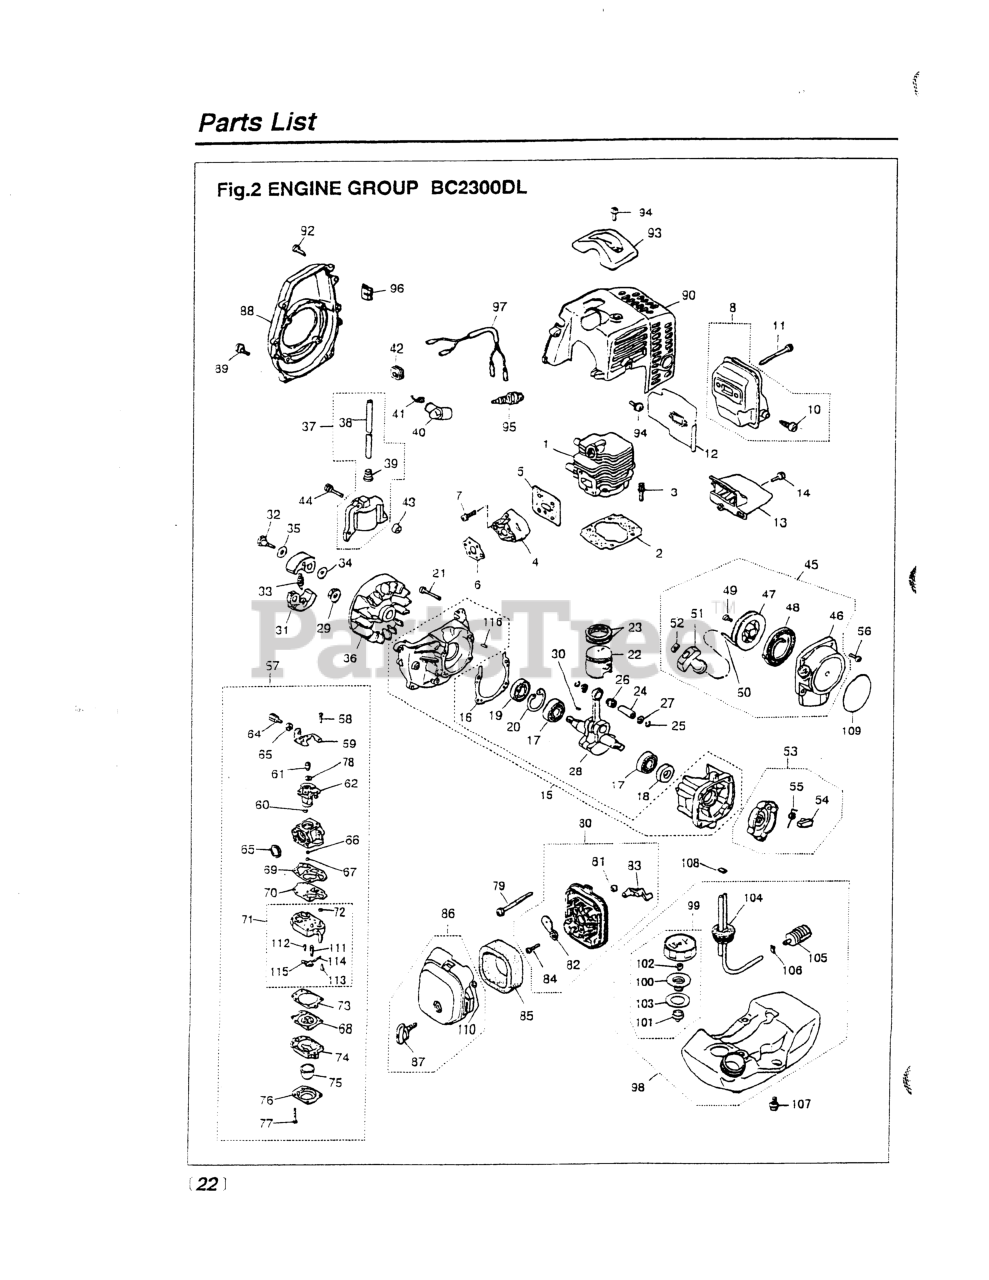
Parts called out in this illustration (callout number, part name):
1	CYLINDER
3	BOLT, M5 X 22
5	GASKET (RPLS -13120)
6	GASKET (REPLACES -13130)
7	SCREW, M5X20 (RPLS.1400-75510)
8	MUFFLER ASSY (RPLS 5501- )
10	ARRESTER (RPLS 5850-15140)
11	BOLT, M5 x 50
12	GASKET, MUFFLER (RPLS -15111)
14	SCREW, M4 X 16
15	CRANKCASE
16	GASKET (RPLS -21140)
17	BEARING
18	SEAL, OIL (RPLS 1100-21210)
19	SEAL, OIL (RPLS 1140-21220)
20	RING, SNAP, M28 x 1.2
21	BOLT, M5 X 30
22	PISTON (REPLACES 1140-41110)
23	RING, PISTON (RPLS 1850-41210)
24	PIN, PISTON 5x8x26
25	RING, SNAP (RPLS 1101-41320)
27	WASHER
28	CRANKSHAFT (RPLS 1850-42000)
30	KEY
31	SHOE (RPLS 1100-51114)
32	BOLT
33	SPRING, CLUTCH (RPLS-51220)
34	WASHER, FLAT (USE 182303)
36	ROTOR
37	COIL ASSY (RPLS 5500-71200)
38	CORD
39	CAP
41	SPRING
42	GROMMET
43	SPACER (RPLS -71260)
44	BOLT
45	RECOIL ASSEMBLY
46	CASE
47	REEL
48	SPRING, SPIRAL
49	SCREW (RPLS -75150)
51	KNOB
52	PLATE, STOPPER
53	PULLEY ASSY (RPLS -75210)
54	RATCHET (RPLS 1850-75220)
55	SPRING, RETURN
56	SCREW, M4 X 16
57	CARBURETOR
58	SCREW
60	RING
61	SWIVEL
62	VALVE ASSY
63	SCREW, CABLE ADJUSTER
64	NUT, CABLE ADJUSTER
65	RING, PACKING
66	RING, O
67	JET
68	DIAPHRAGM (USE 4810-81260)
69	GASKET, PUMP
70	DIAPHRAGM
71	BODY, PUMP
73	GASKET, DIAPHRAGM
74	BODY, PURGE
75	PUMP, PRIMING
76	COVER, PUMP
77	SCREW
78	WASHER
79	SCREW, M5 x 60
80	BODY-A (RPLS -82101)
81	SLEEVE
82	PLATE, CHOKE (RPLS-82130)
83	LEVER, CHOKE
84	SCREW (REPLACES 50030272)
85	ELEMENT
87	KNOB (RPLS -82220)
88	COVER, FAN (RPLS-31110)
89	SCREW, M5X20 (RPLS.1400-75510)
90	COVER, ENGINE (RPLS -32111)
91	SCREW, M5 x 12
92	SCREW, HOUSING
93	GUARD, PLUG
94	SCREW,M5 X 14 (RPLS 1400-15510
97	CORD COMP (RPLS -73200)
101	HOLDER, CAP
102	VALVE (NLA WHEN OUT)
103	PACKING
104	PIPE COMPLETE
105	FILTER (RPLS 1850-85300)
106	CLIP (REPLACES 2841-31280)
107	SCREW
108	CLIP
109	LABEL, RECOIL (RPLS -91121)
110	RING
111	VALVE, INLET
112	SPRING, METERING LEVER
113	SCREW, METERING LEVER PIN
114	PIN, METERING LEVER
115	LEVER
116	PIN
